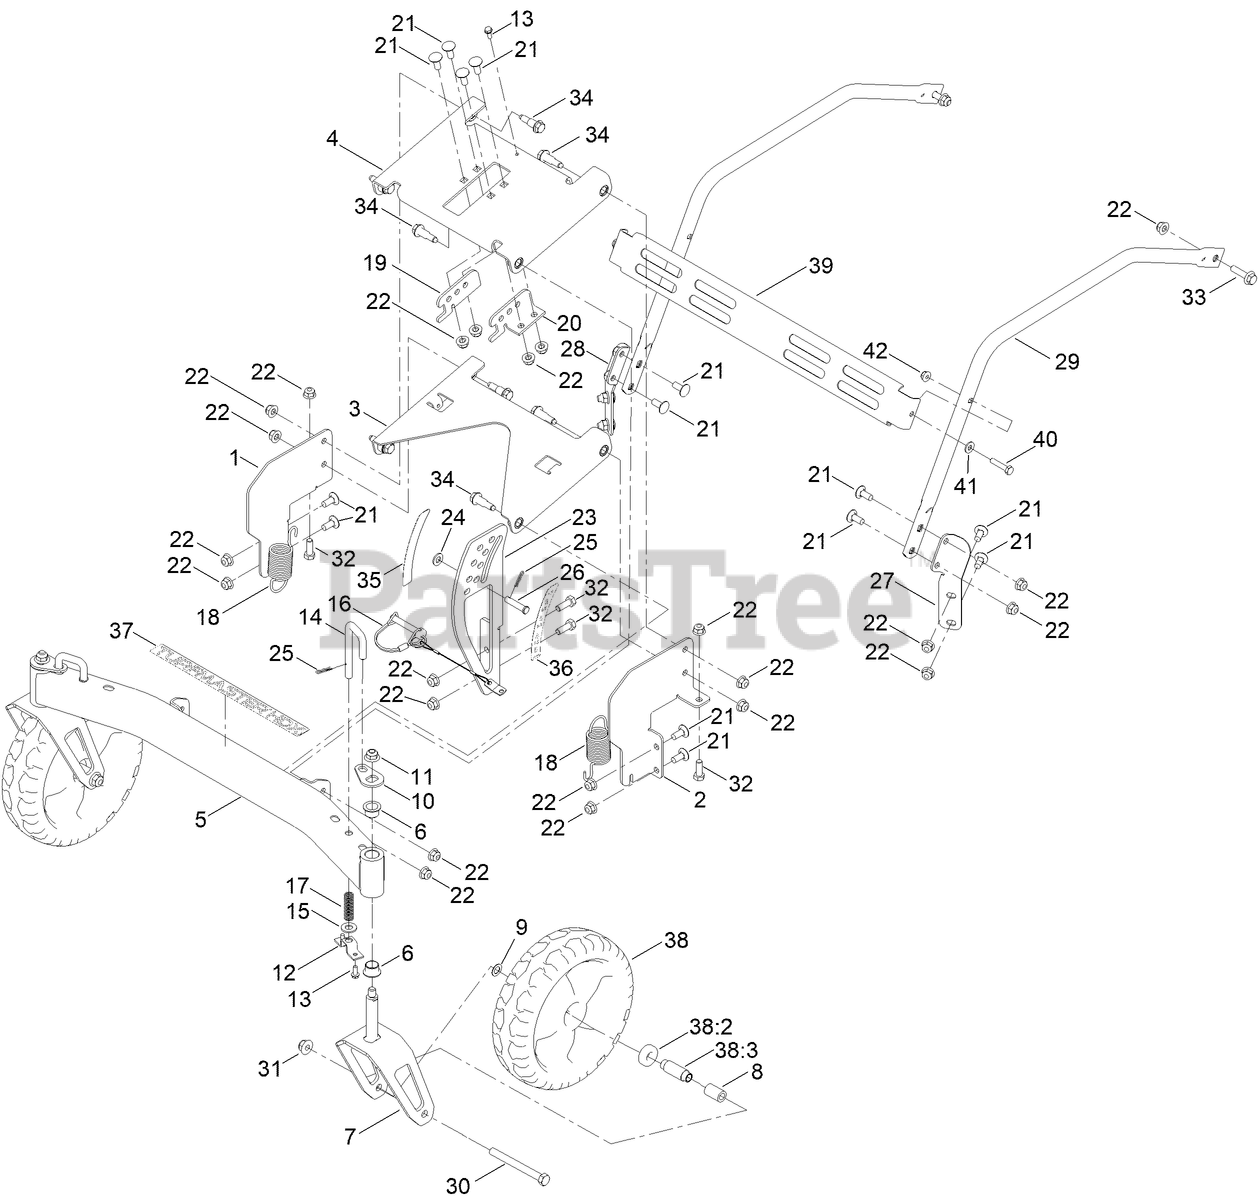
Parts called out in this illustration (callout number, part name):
1	CASTER DECK BRACKET
2	CASTER DECK BRACKET
3	LINK PLATE ASM [RED]
4	LINK PLATE ASM [RED]
5	FRONT AXLE
6	BUSHING
7	CASTER FORK
8	SPACER
9	WASHER-FLAT
10	LOCKING PLATE
11	NUT-HF, NI
12	CASTER PIN BRACKET
13	SCREW-TAPTITE
14	CASTER LOCK PIN
15	WASHER-FLAT
16	LOCKING PIN W/LANYARD
17	SPRING-COMPRESSION, PIN
18	SPRING-EXTENSION, HOC ASSIST
19	HOC POSITION PLATE RH
20	HOC POSITION PLATE LH
21	SCREW-CARR
22	NUT-HF, NI
23	HOC PLATE
24	WASHER-PLAIN
25	PIN-HAIR
26	PIN-CLEVIS
27	BRACE BRACKET LH
28	BRACE BRACKET RH
30	SCREW-HH
31	NUT-HF, NI
32	SCREW-HH
33	SCREW-HHF
34	BOLT-SHOULDER, FLANGE
35	DECAL-HOC
36	DECAL-HOC
37	DECAL-TURFMASTER HDX
38:2	BEARING-BALL
38:3	SPACER
40	SCREW-HH
41	WASHER-FLAT
42	NUT-HF
